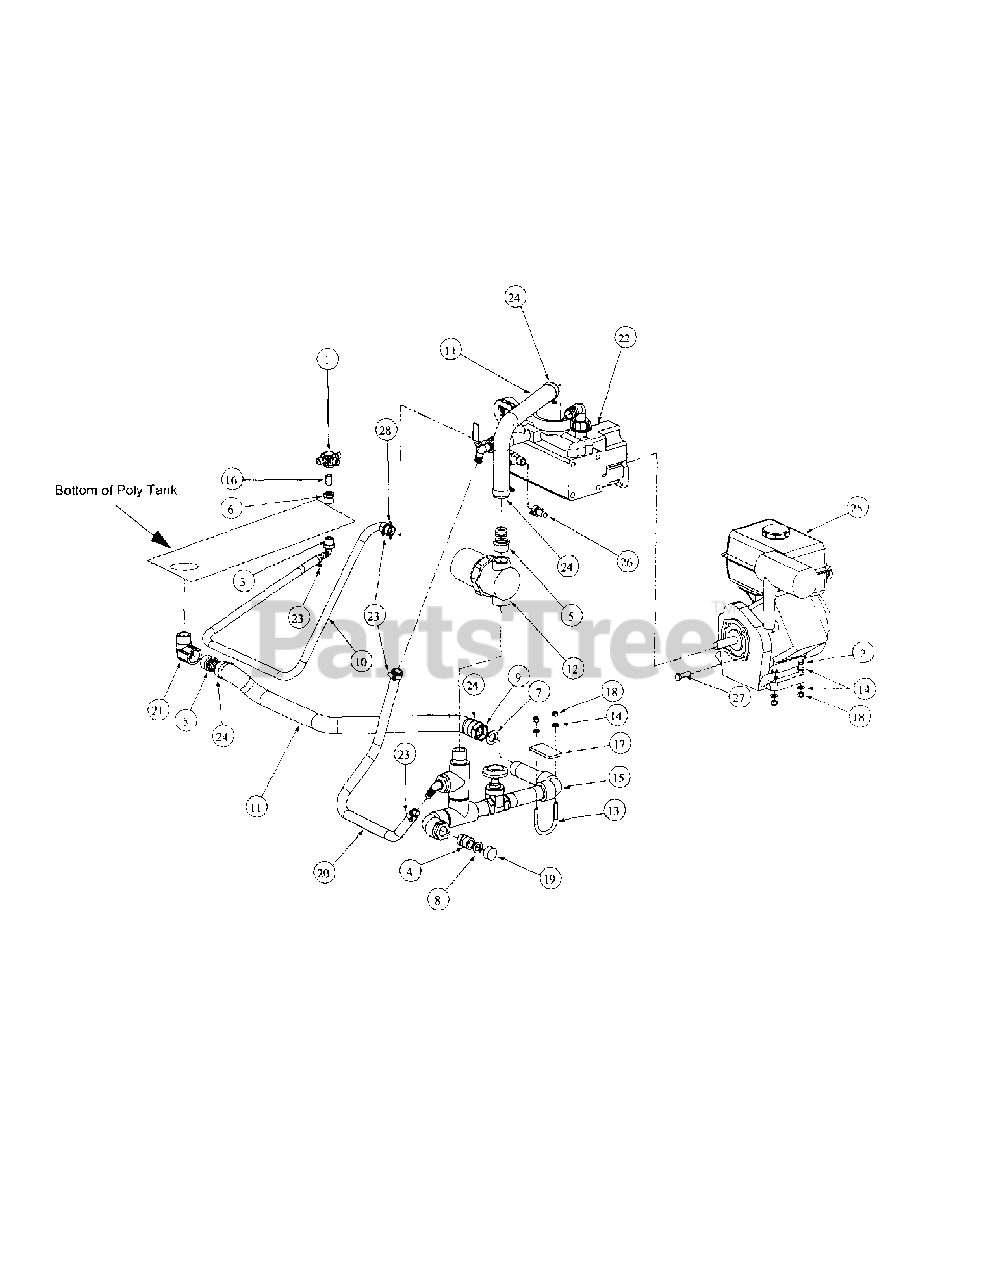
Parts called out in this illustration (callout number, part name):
1	Agitator, Jet
2	HHCS, 5/16-18, 1-3/4
3	Hose Barb, 1/2 NPT, 1/2 Nylon
4	Adapter, 3/4 NPT, 3/4 Hose
5	Hose Barb, 1" NPT, 1" Nylon
6	Adapter, 1/4 NPT, 1/2 NPT
7	Washer, Hose 1"
8	Washer Hose, 3/4" Rubber
9	Repair Coupling, Hose
10	Hose, 1/2" sold by the ft.
11	Hose, 1", Spiraflex sold by the ft.
12	Strainer, 30 Mesh-SS
13	U-Bolt, 5/16-18 x 2
14	Flat Washer, 5/16 SAE
15	Manifold Assembly
16	Nipple, 1/4 NPT
17	Rubber Pad 1/4" x 1-1/2" x 3"
18	Nut, 5/16-18, Nylock
19	Hose Cap, 3/4"
20	Hose 5/8" PVC sold by the ft.
21	Street Elbow, PVC 1" NPT x 1"
22	Pump Assembly
23	Hose Clamp, 1/2, 7/8
24	Hose Clamp, 7/8, 1-1/4
25	Engine, 5.5HP Kawasaki
26	Fittings
27	Button Head Bolt, m8-1.25 x 25 mm
